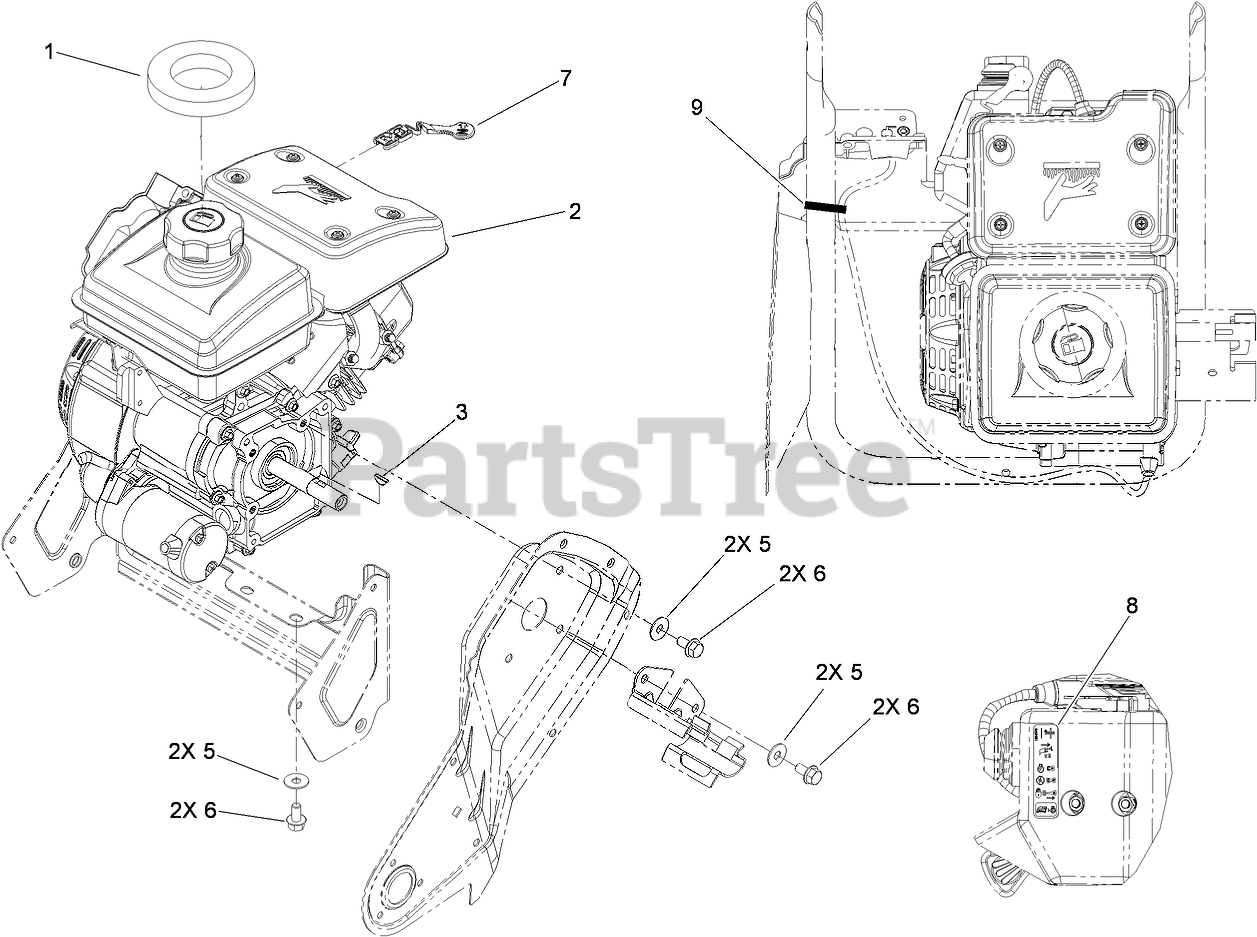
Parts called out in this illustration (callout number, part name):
1	SEAL-TANK
2	ENGINE-LC154FDS-1
3	KEY-WOODRUFF
5	WASHER-BELLEVILLE
6	SCREW-HHF
7	LEVER-CHOKE
8	DECAL-CONTROL, ENGINE
9	TIE-CABLE
